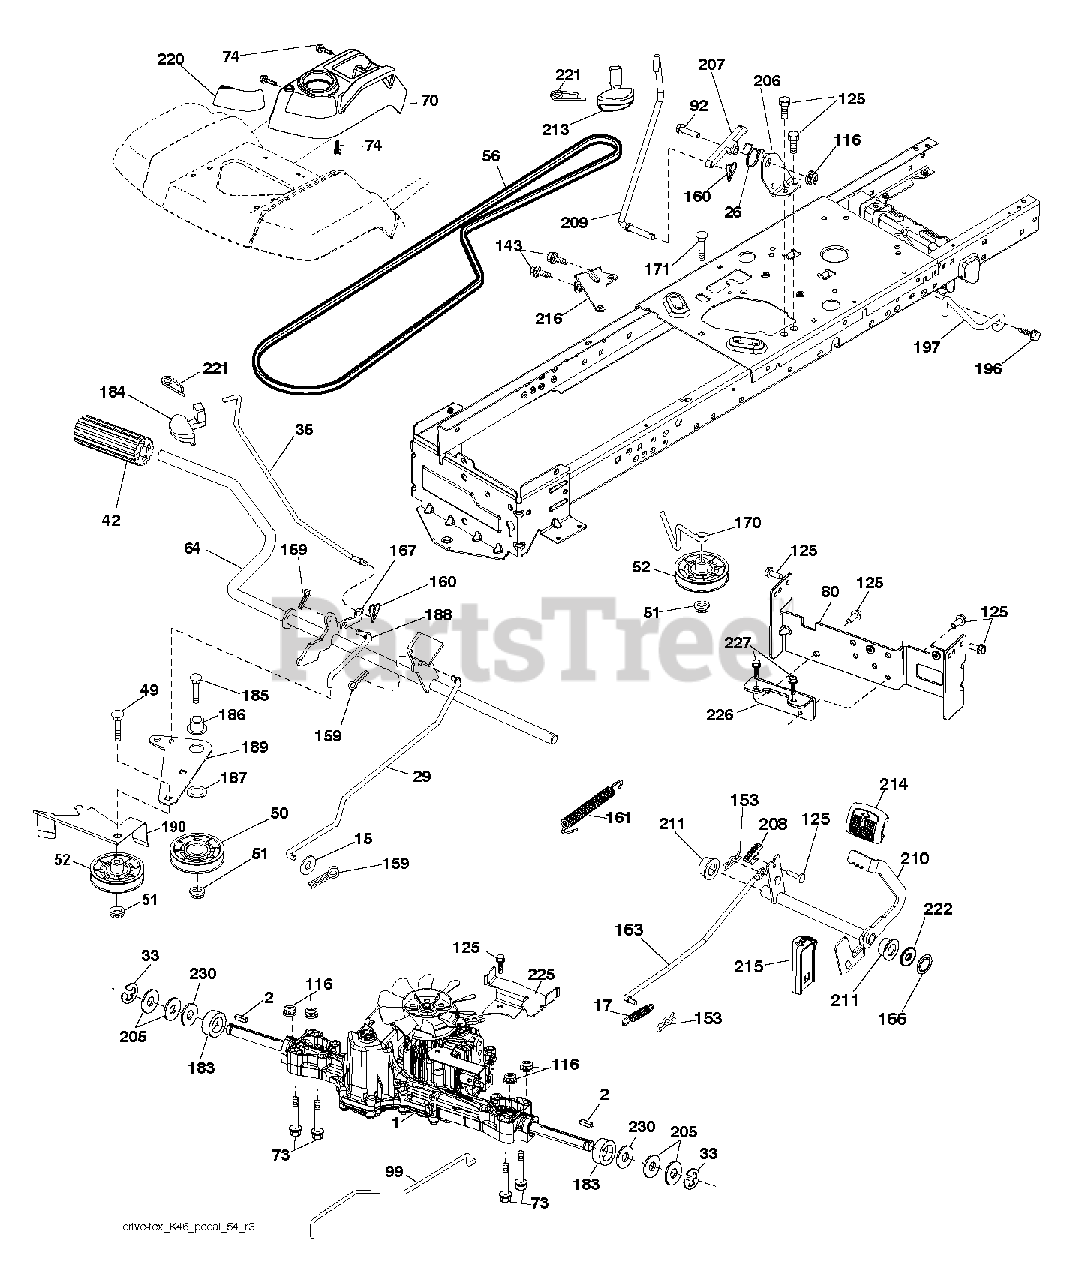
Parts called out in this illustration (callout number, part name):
2	SQUARE KEY
15	WASHER
17	SPRING.BRAKE.K46.GREEN
26	SPRING.RETURN.CRUISE
29	ROD.BRAKE.K46
35	ROD.BRAKE.PARTK.HUSQ.TEX
42	PEDAL COVER T
50	IDLER.FLAT.910.OFFSET
51	NUT LOCK FLG 3/8-16 UNC
52	IDLER.V-GROOVE.910.OFFSET
56	V-BELT.MOWER.92.40.42/K46
64	SHAFT.ASM.PEDAL.BRK.CNTR
70	CONSOLE.ASM.RH.GT.FC.HUSQ
74	SCREW.HI-LO.CONSOLE
80	STRAP.TORQUE.K46.K57R.TT
92	BOLT
99	ROD.SPRING.BYPASS.K46.LT.Z
116	NUT LOCK HEX FLANGE 5/16-18
125	SCREW
143	SCREW LT
153	RETAINER M
159	COTTER PIN
160	RETAINER CLIP
161	SPRING, RETURN LT
163	ROD.CONTROL.K57R.K46
166	NUT.PUSH.625
167	LATCH.BRAKE.SPRING
170	KEEPER.V-IDLER.CENTER.
183	SPACER AXLE
184	RB HANDLE.PARKG.BRK.HUS/PRED
186	SPACER.RETAINER
187	WASHER 12/32X2X10GA
188	RP LINK.CLUTCH.GROUND.DRIVE
189	BELLCRANK.GROUND.DRIVE.TEX.
190	KEEPER.BELLCRANK.DRIVE
196	SCREW 3/8-16X1
197	LINK.CLUTCH.ANIT-ROTAT
206	BRKT.MOUNT.LATCH.CRUIS
207	LATCH.CONTROL.CRUISE
208	GEAR.SECTOR.CONTROL.CR
209	ROD.CONTROL.CRUISE.GT.
210	ROCKER.ASM.PEDAL.CONTR
211	BEARING.NYLON
213	KNOB.CONTROL.CRUSIE.HU
214	PEDAL.FORWARD.PAD.TEX
215	PEDAL.REVERSE.TEX.GT.4
216	BRACKET.PULLEY.IDLER.W/TEX
220	REFLECTOR.RH.TEX GT
221	RETAINER.SPRING.CLIP.H
222	WASHER 21/32 X 1-1/4 X 10 GA.
225	KEEPER.BELT.TRANSAXLE.K46
226	BRACKET.MOUNT.TORQUE.K46.TLT
227	SCREW
230	WASHER.HARDENED
